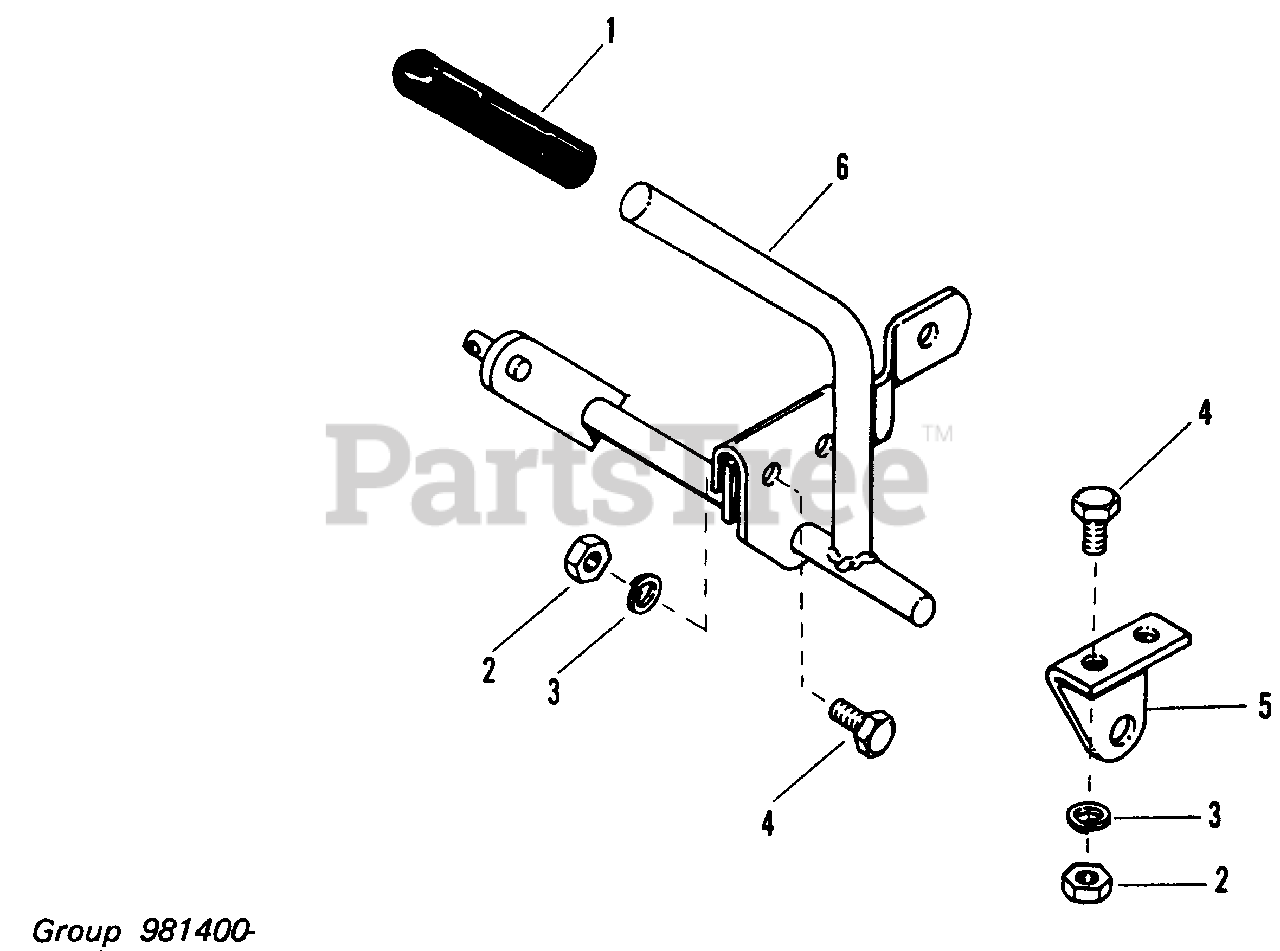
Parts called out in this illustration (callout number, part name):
1	HANDLE, Grip
2	NUT, Hex Full, 1/4-20
3	LOCKWASHER, 1/4
4	CAPSCREW, Hex, 1/4-20 x 5/8
5	SUPPORT, Clutch
6	CLUTCH LEVER ASSEMBLY
